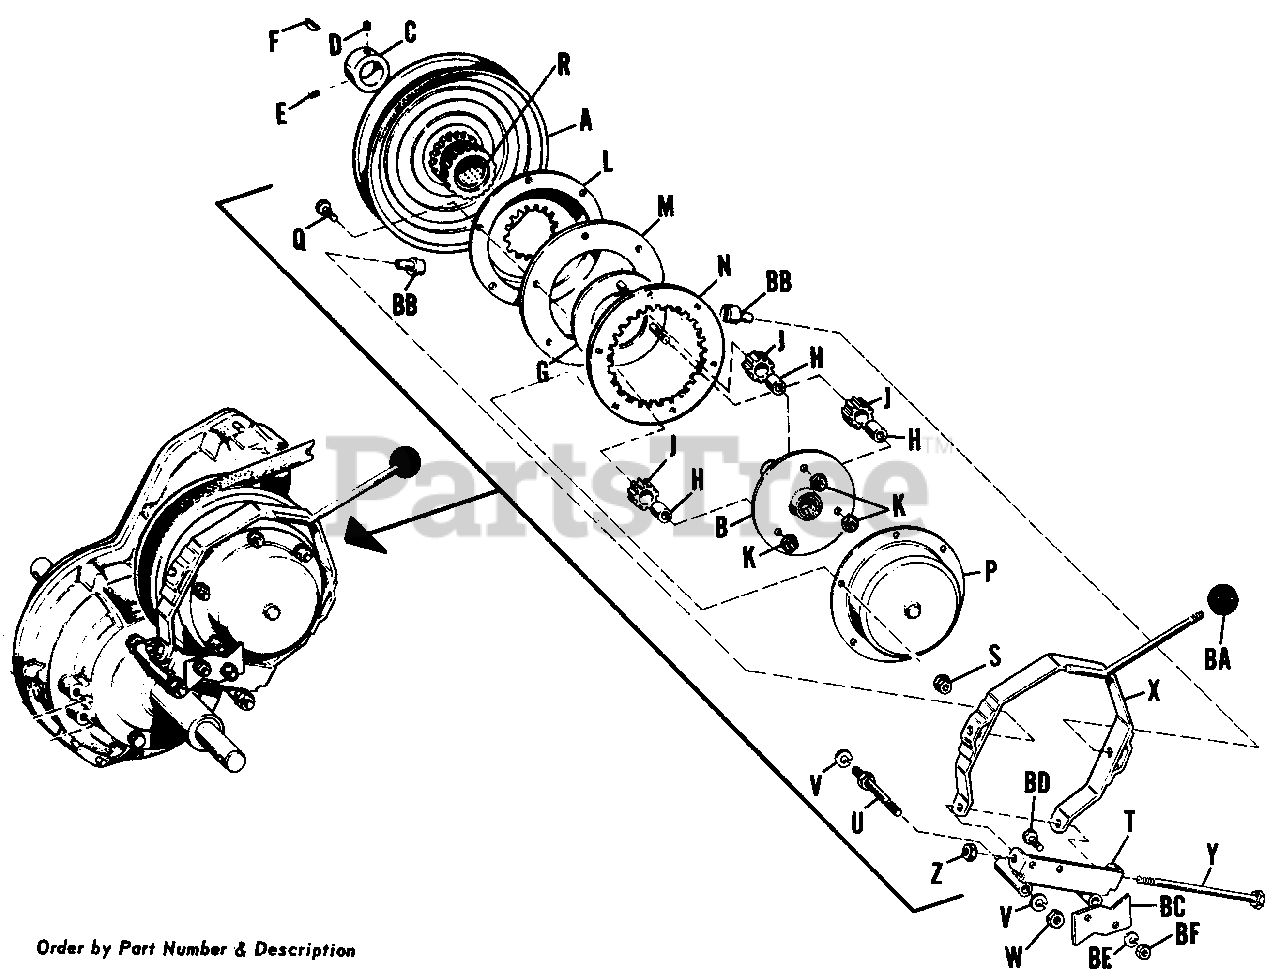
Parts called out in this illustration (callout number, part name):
A	Pulley & Gear Assembly
B	Spider & Bearing Assembly
D	Set Screw, Socket Hd., Cup Pt., 5/16"-18 x 1/2" lg.
E	Set Screw, Socket Hd., Cup Pt., 5/16"-18 x 3/8" lg.
F	Woodruff Key
G	Ring Assembly
K	Hex Nut, Full, 3/8"-16
L	Cover Assembly
M	Shift Ring
N	Gear Ring
P	Cover Assembly, Right Hand
Q	Hex Capscrew, 1/4"-20 x 5/8" lg.
R	Bushing (2 Required)
S	Nut Flange, Whiz Lock, 1/4"-20
T	Pivot Bracket Assembly
V	Lock Washer, 3/8"
W	Hex Nut, Full, 3/8"-16
X	Shift Fork Assembly
Y	Hex Capscrew, 5/16"-18 x 6-1/2" lg.
Z	Hex Nut, Full, Lock, 5/16"-18
BB	Shift Pivot
BD	Hex Capscrew, 5/16"-18 x 3/4" lg.
BE	Lock Washer, 5/16"
BF	Hex Nut, Full, 5/16"-18
